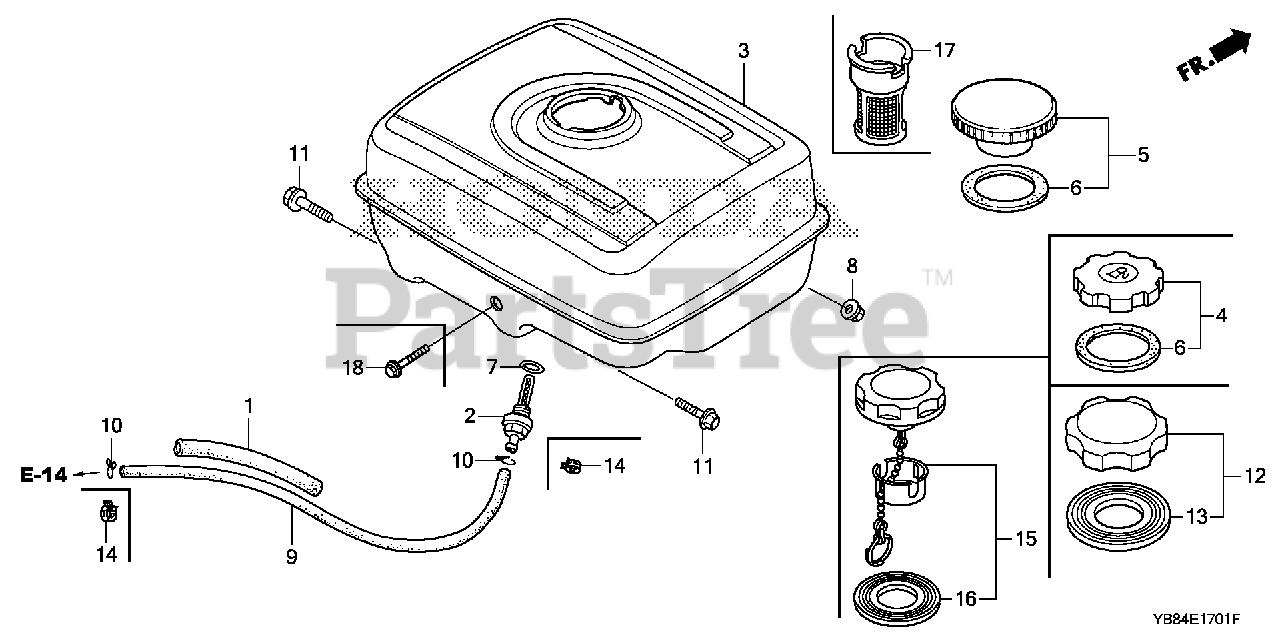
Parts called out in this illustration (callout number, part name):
1	RUBBER, SUPPORTER (107MM)
2	JOINT, FUEL TANK
3	TANK, FUEL *NH31* (MCKINLEY WHITE)
7	O-RING (14MM) (ARAI) Use up to Engine SN 2949254.
7	O-RING (14MM) (NOK)
8	NUT, FLANGE (6MM)
14	CLIP, TUBE (D8)
15	CAP, FUEL FILLER
16	GASKET, FUEL FILLER CAP (39X62X3) (TOUYOUSYA)
16	GASKET, FUEL FILLER CAP
17	FILTER, FUEL
18	BOLT, FLANGE (6X29)
